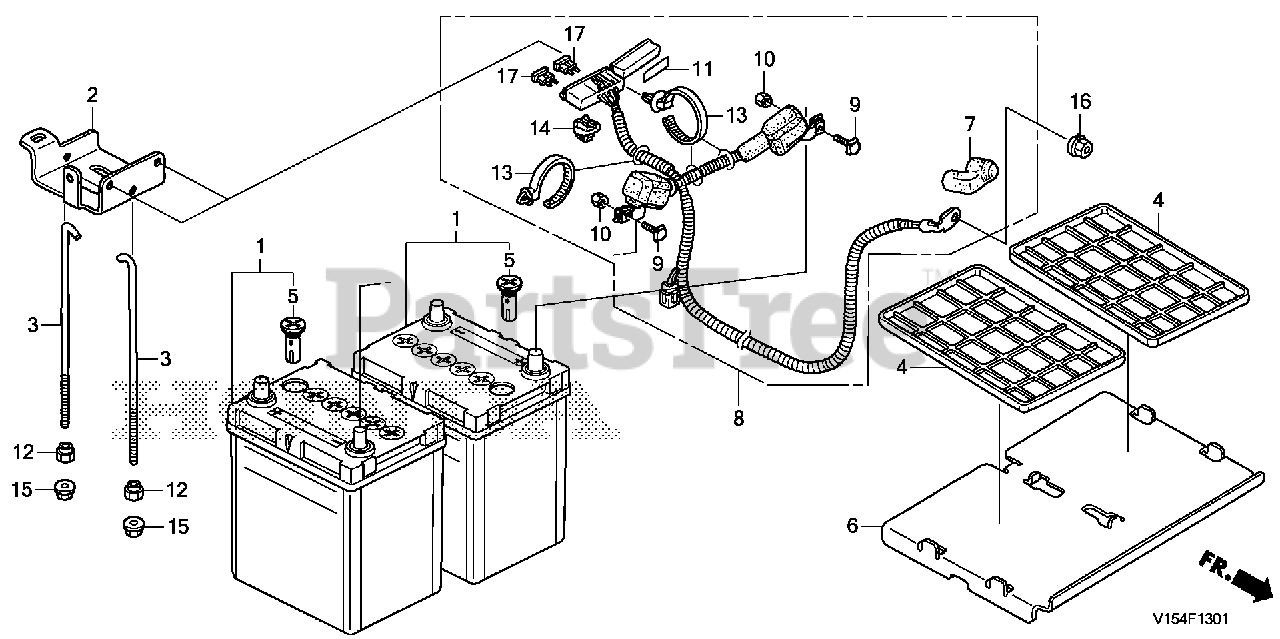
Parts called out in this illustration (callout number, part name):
1	BAT (38B19R<S>-MF)-MF) (FURUKAWA) (MSDS)
2	PLATE, BATTERY SETTING
3	BOLT, BATTERY SETTING
4	BOX, BATTERY
5	PLUG, VENT (MF) (FURUKAWA)
7	COVER, STARTER TERMINAL
8	CABLE ASSY., BATTERY JOINT
9	BOLT, BATTERY TERMINAL
10	NUT, BATTERY TERMINAL
11	LABEL, BLADE FUSE
12	NUT, SPECIAL (6MM)
13	CLIP, HARNESS BAND (145MM) (BLACK)
14	CLIP, CONNECTOR (ORANGE)
15	NUT, FLANGE (6MM)
16	NUT-WASHER (8MM)
17	FUSE, MINI (30A)
